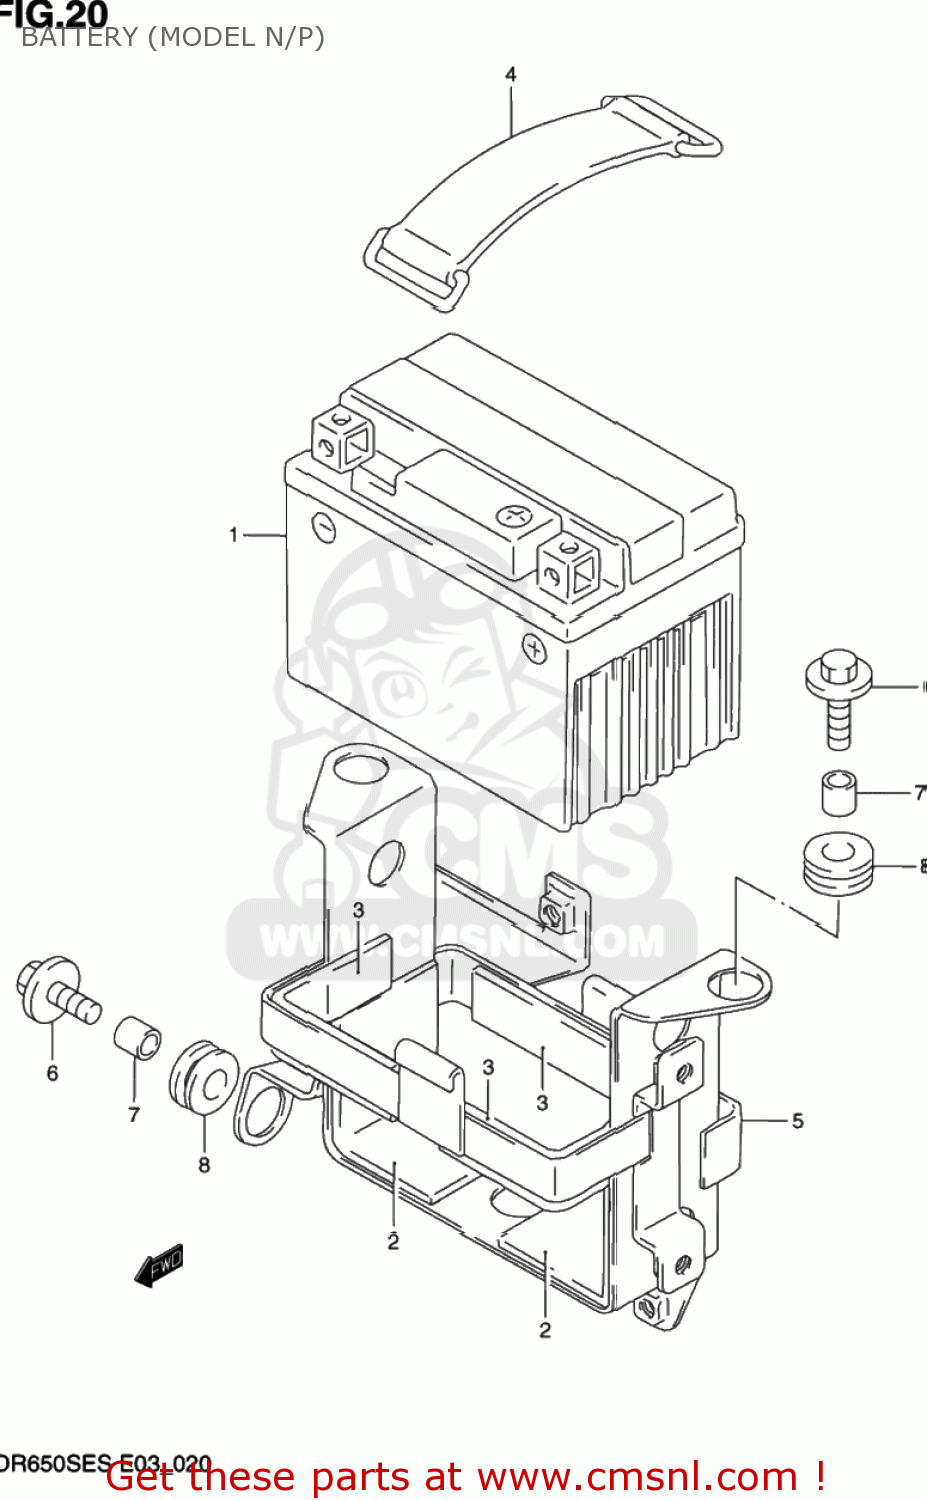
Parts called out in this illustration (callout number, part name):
1	BATTERY ASSEMBLY (12V) YT4
2	PROTECTOR(170X95X3.0)
3	PROTECTOR,20X9
4	BAND
5	HOLDER COMP,BATTERY
6	BOLT
7	SPACER(6.1X9X7.5)
8	CUSHION
